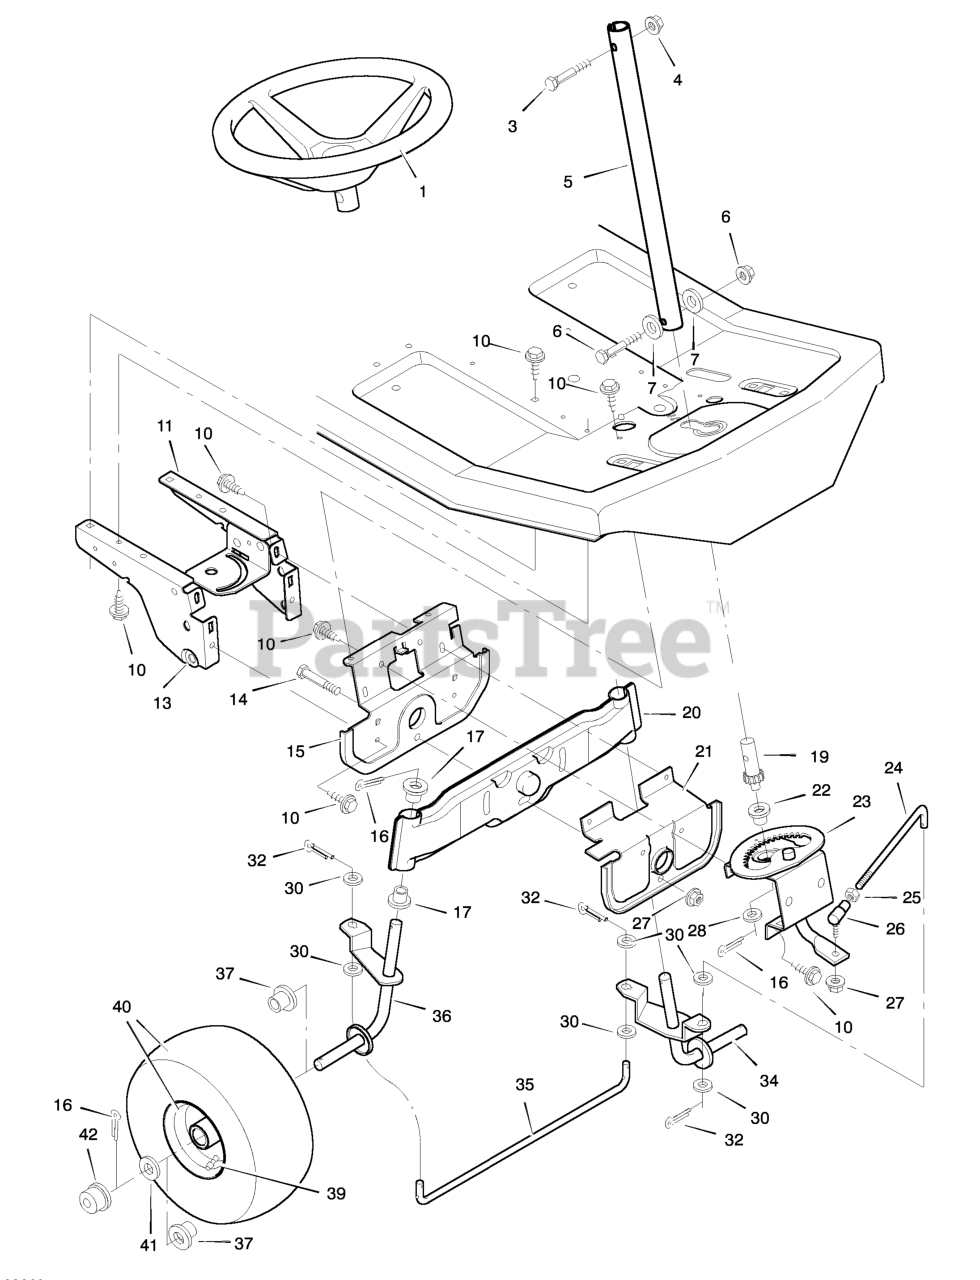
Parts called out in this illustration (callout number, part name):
1	Steering Wheel
3	Bolt, Hex
4	Locknut, Flange
5	Post, Steering
6	Nut, Hex
7	Washer
8	Cover, Steering Post
9	Bearing
11	Plate, Left Suspension
13	Plate, Right Suspension
14	Bolt, Hex
15	Support, Front Axle
16	Pin, Cotter
17	Bearing, Spindle
19	Gear, Pinion
20	Axle Assembly, Front
21	Hanger Assembly, Front Axle
22	Bearing
23	Sector Assembly
24	Rod, Drag Link
25	Nut, Hex
26	Ball Joint, Steering
27	Locknut, Flange
32	Pin, Cotter
34	Spindle Assembly, Left
35	Rod, Tie
36	Spindle Assembly, Right
37	Bearing, Wheel
39	Valve Stem
40	Wheel & Tire Assembly
42	Cap, Hub
